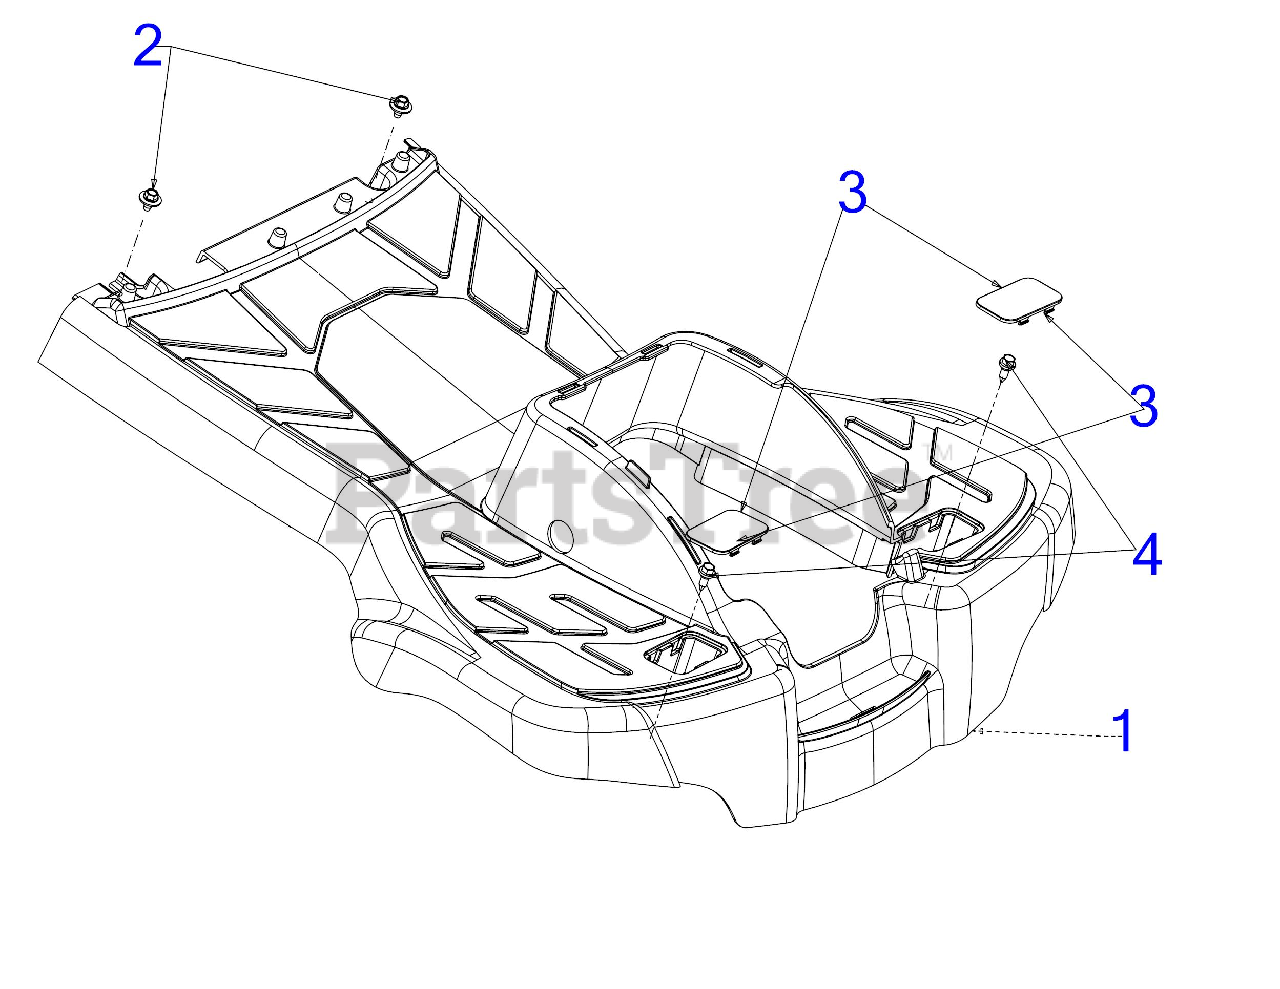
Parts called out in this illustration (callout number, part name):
1	RUNNINGBOARD
2	SCREW 1/4-20 x .50
3	RUNNING BOARD PLUG
4	SHOULDER SCREW
